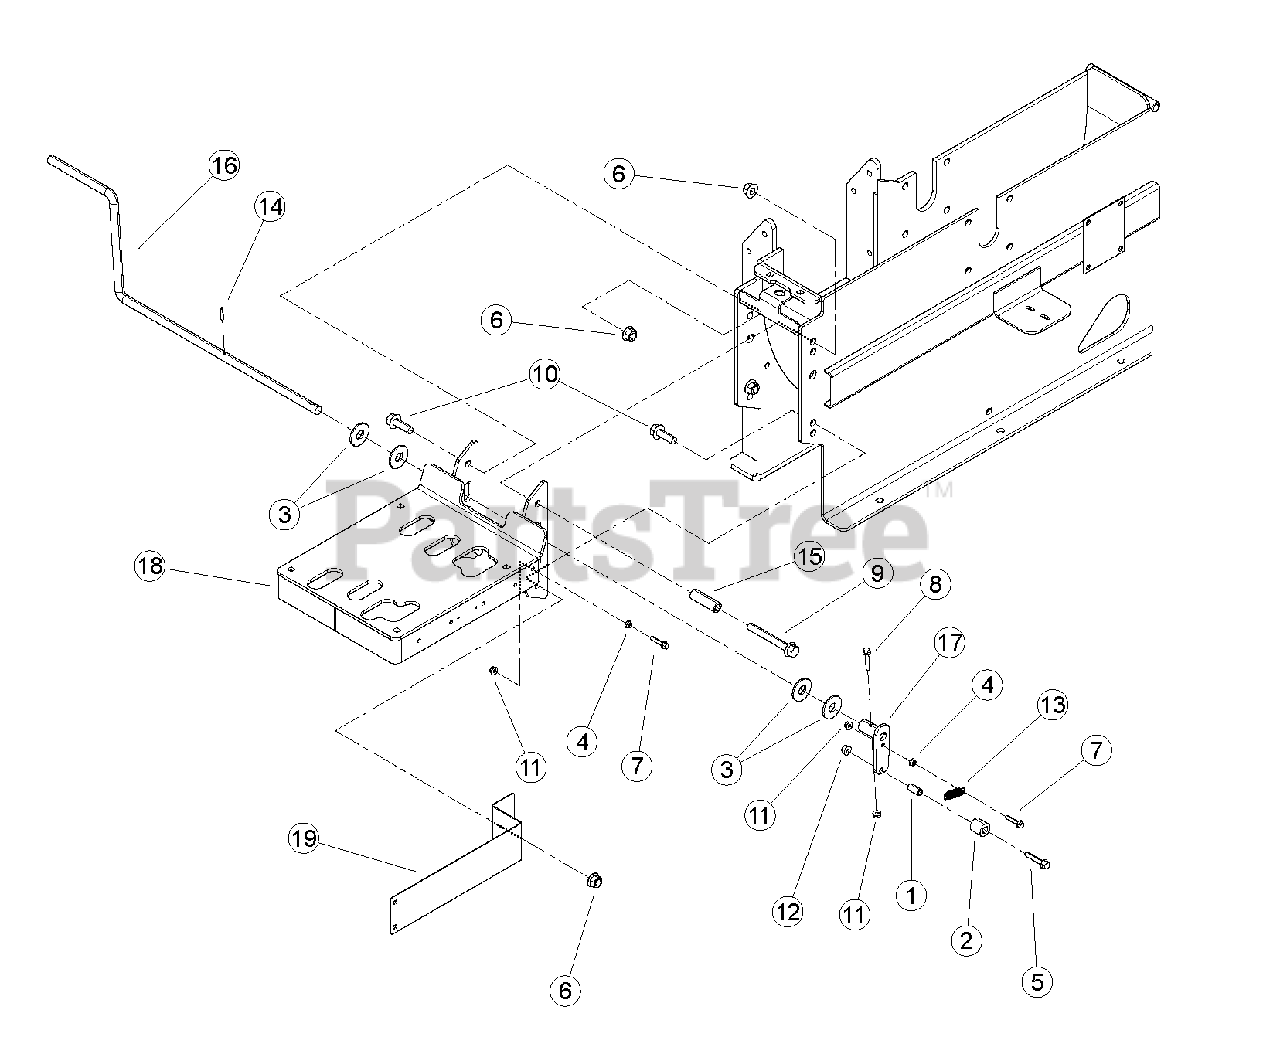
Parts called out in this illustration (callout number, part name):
1	SPACER, 0.5 X 1.00
2	ROLLER, 0.5 X 1.00 X 1.00 NYLON
3	WASHER, 5/8" FLAT ZP
4	NUT, 1/4"-20 SERRATED FLANGE NC ZP
5	BOLT, 5/16 X 1-3/4 FLANGE NC
6	NUT, 1/2-13 NYLOCK FLANGE
7	BOLT, 1/4 X 1-1/4 FLANGE NC
8	BOLT, 1/4 X 1-1/2 FLANGE NC
9	BOLT, 1/2-13 X 4 HWH GR5 CZP
10	BOLT, 1/2-13 X 1-1/2 GR5 FLANGE NC
11	NUT, 1/4-20 NYLOCK-FLANGE
12	NUT, 5/16-18 NYLOCK-FLANGE
13	SPRING, 1/2 X 2.00 LG, ZP
14	PIN, ROLL 3/16 X 1"
15	SPACER, .75 X 2.06
16	HANDLE, ENGAGEMENT
17	WELDMENT, SHAFT ENGAGEMENT ARM
18	WELDMENT, ENGINE BASE
19	SHIELD, HYD PUMP
